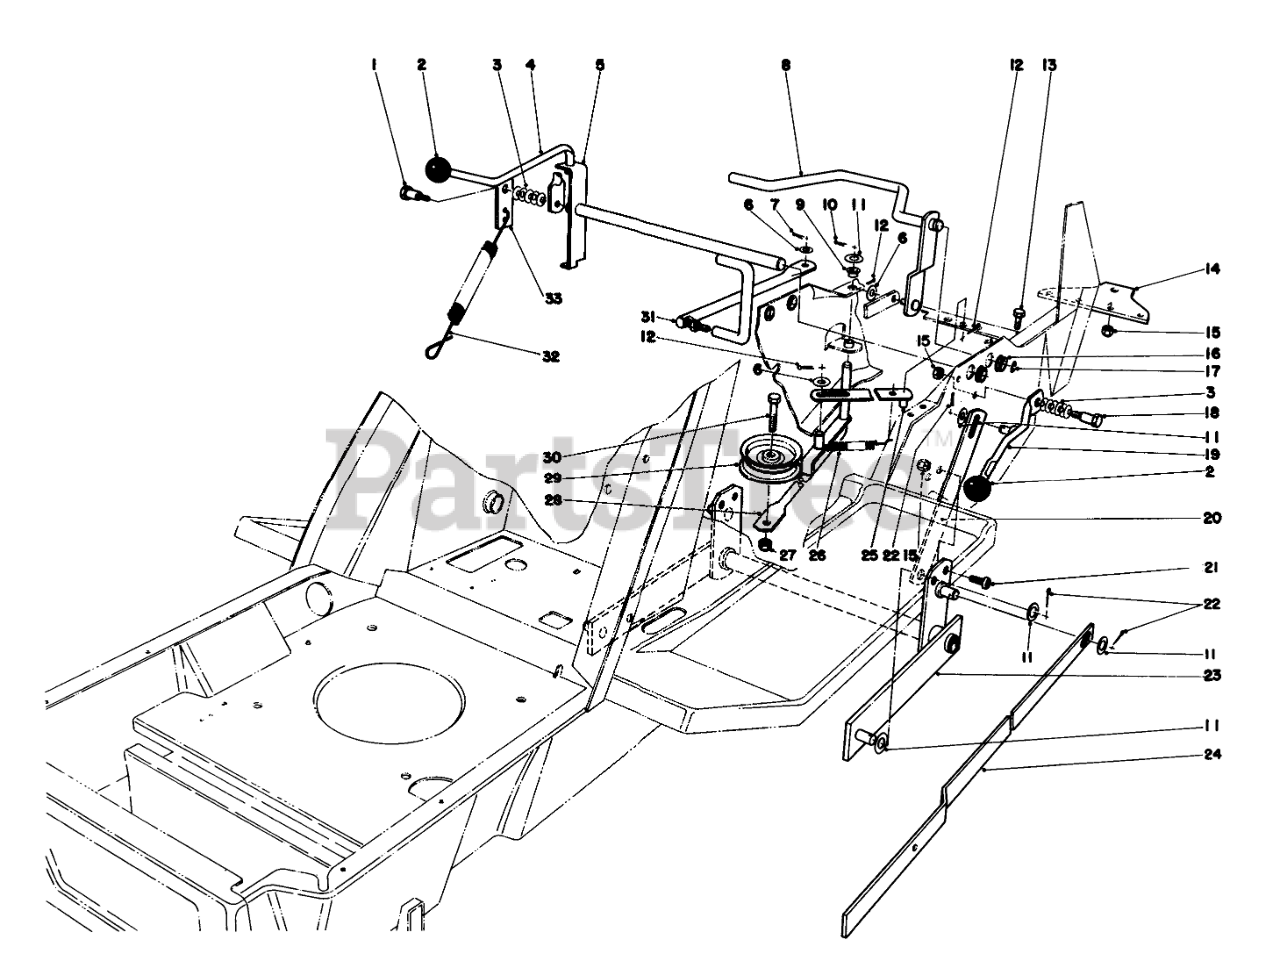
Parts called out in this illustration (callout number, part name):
1	BOLT-SHOULDER
3	WASHER-BELLEVILLE
4	SHIFT LEVER BO
5	Shim Lever
6	WASHER-PLAIN
7	PIN-COTTER
8	CLUTCH ACTUATOR WA B
9	BUSHING-NYLINER
10	PIN-COTTER
11	WASHER-FLAT
12	PIN-COTTER
13	SCREW-HHF
14	HITCH PLATE R
15	NUT-LOCK, NI
16	Nyliner
17	E-RING
18	SHOULDER BOLT
19	Handle-Height of Cut
20	HOC LINK B
21	SCREW-HSBH
22	PIN-COTTER
23	Bar-Pivot
24	Link-Rear Scissors
25	SPRING RET WA B
26	DECK TENSION SPRNG O
27	NUT-LOCK, CONE
28	IDLER ARM WA BO
29	IDLER PULLEY
30	SCREW-HH
31	SHIFT ARM BO
32	EXT SPRING O
33	Bracket Counterbalance Spring
